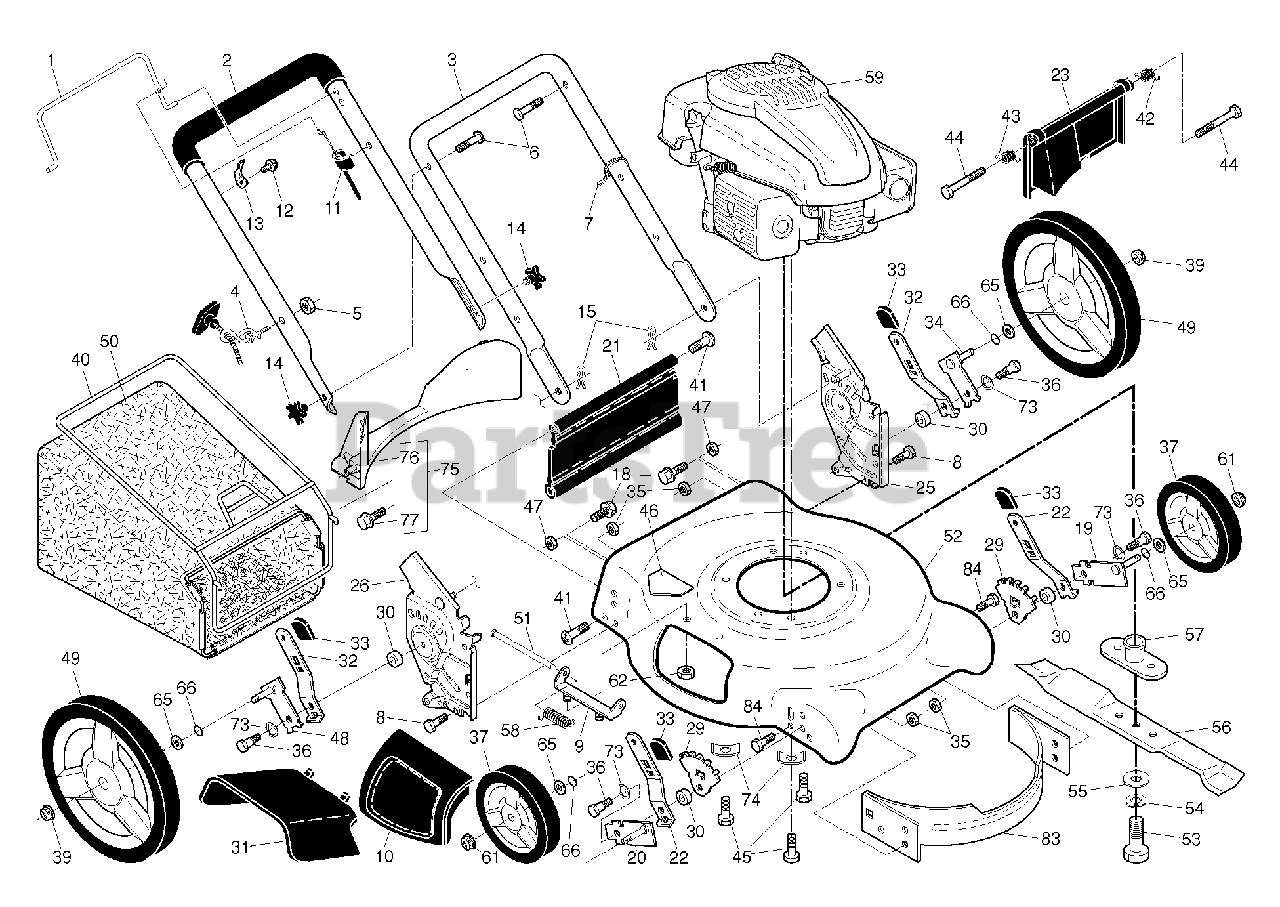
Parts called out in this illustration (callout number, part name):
1	CONTROL BAR
2	HANDLE.UPPER.W/GRIP.FGD/PUSH
3	HANDLE.LOWER.D-STRAIT.GREY
4	RB GUIDE.ROPE.STD.BLK.ZIN WSL
5	NUT
6	BOLT, HANDLE 5/16-18X1.75
7	TIE GUIDE
8	BOLT
9	BRACKET.ASM.HOUSING.EZ.MUL
10	RP DOOR.MULCH.21".REAR.PUSH.GR
11	ENG ZONE CNTRL CB
13	BRACKET.UPSTOP.RT
14	KNOB.HANDLE.PLASTIC.STAR.BLACK
15	HAIRPIN COTTER
18	SCREW 1/4X20
19	AXLE ARM ASSY FRONT LH
20	AXLE ARM ASSY FRONT RH
21	RP_KIT.SKIRT.21 DOMED.W/LIP
22	SELECTOR SPRING, FRONT
23	REAR DOOR ASSY
25	RP BRACKET.ASM.HND.HW.21.LT.
26	RP BRACKET.ASM.HAND.HW.21.RT.O
29	WHEEL ADJ BRACKET FRONT
30	SPACER.HEIGHT.ADJUSTER(2 2)3 2
31	DEFLECTOR.CLIPPING.21.GREY
32	SPRING.SEL.EXT.21.DOMED.12/14
33	SELECTOR KNOB
34	AXLE ARM ASSY REAR LH
35	NUT.FLANGE.HEX.5/16X18.BLACK
36	SHOULDER BOLT 5/16-18
37	WHEEL & TIRES ASSY, FRONT
39	NUT.HEX.FLANGE.3/8-16.LOCKNUT
40	FRAME.BAG.21.REAR.DOMED.PUSH
41	SCREW.1/4-20X21/4.HEX.
42	SPRING.LH.22.REAR.DOOR.EZ.EMPT
43	SPRING.RH.22.REAR.DOOR.EZ.
45	BOLT 3/8-16X1-1/8
46	DANGER DECAL
47	NUT.LOCK.5/16-18
48	AXLE ARM ASSY REAR RH
49	WHEEL ASSY
50	GBAG.2323247.SILVER
51	ROD.HINGE.COMBI-C
52	HOUSING.21.M/C.DOME.ORANGE
53	SCREW, HEX HD 3/8-24 X 1-3/8
54	LOCKWASHER
55	WASHER,HARDEN
56	BLADE.21.PUSH/RWGD/FWGD
57	ADAPTER.BLADE.W/KEY.25MM.CE
58	TORSION SPRING
61	NUT.HEX.FLANGE.3/8-16.LO(3 2)
62	LOCKNUT.NYLOC.1/4-20
66	O-RING..070X.487.NEOPRENE
73	WASHER.CURVED.CYLINDRICAL
74	WASHER.ENGINE.BZP
75	KIT.BAFFLE.REAR.PLASTIC.21.RD
76	BAFFLE.REAR.PLASTIC.21.RD.ECON
77	SCREW.HX.13X.750
83	BAFFLE.FRONT.21.DOME.US
84	BOLT.5/16HEX.WHS.HD
